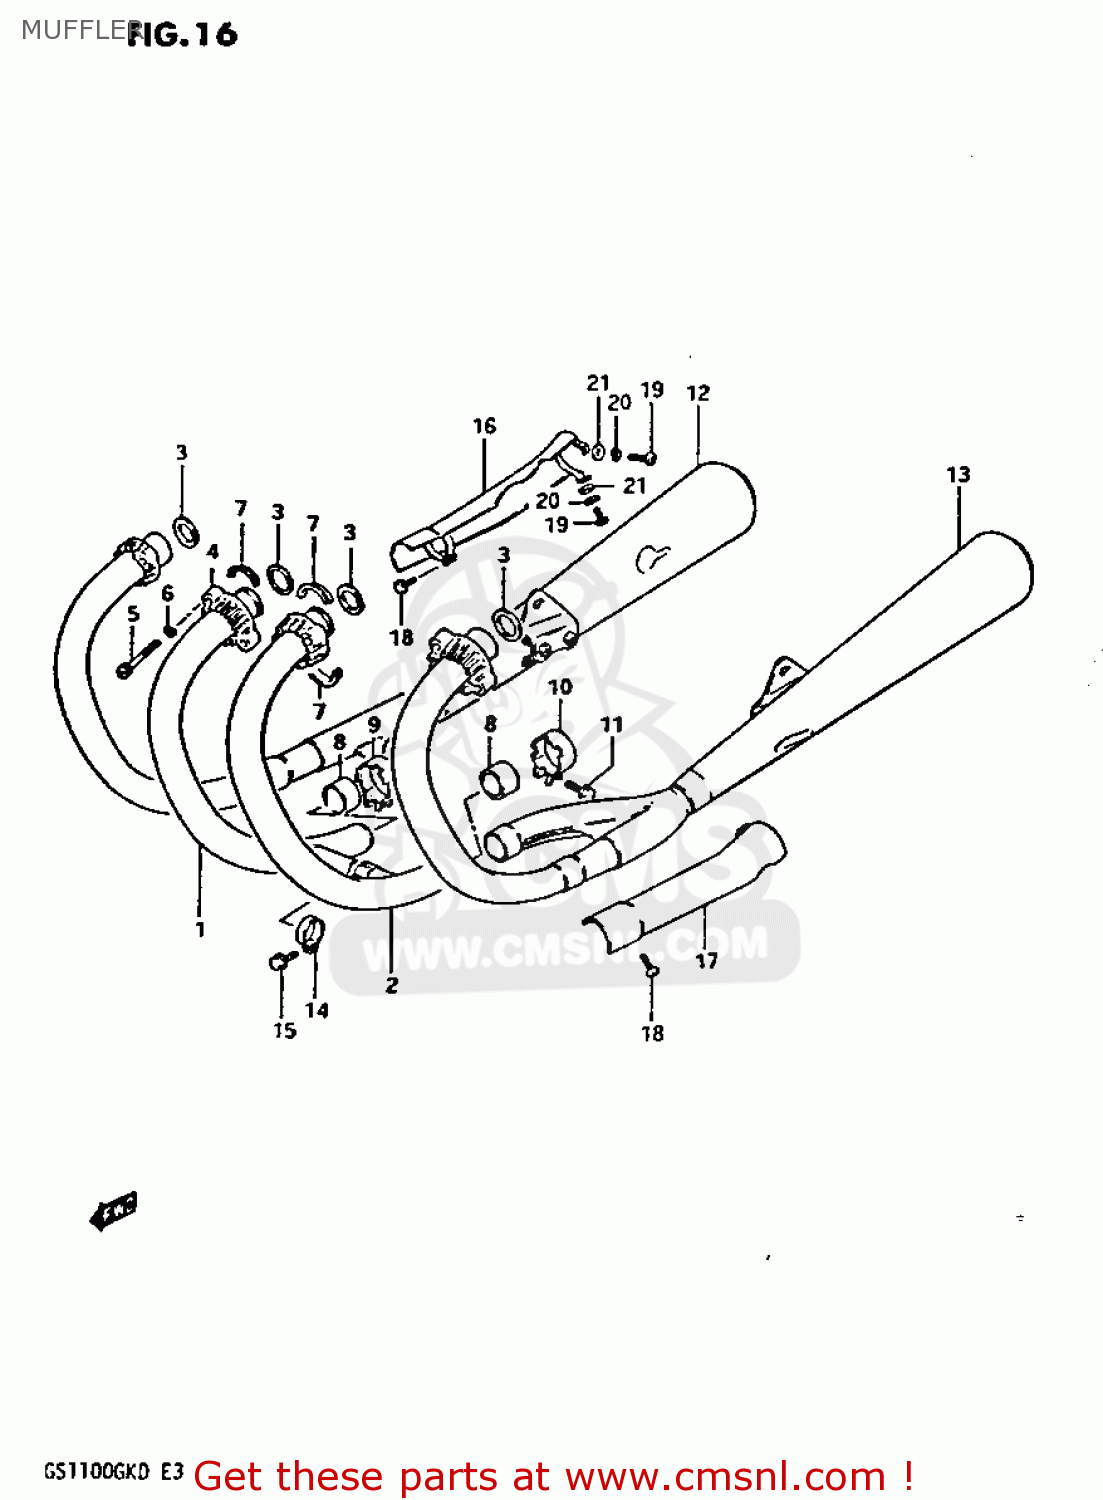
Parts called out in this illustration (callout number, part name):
1	PIPE,EXHAUST,CENTER,RIGHT
2	PIPE,EXHAUST,CENTER,LEFT
3	GASKET,EXHAUST PIPE (NAS)
4	CLAMP(H:21)
5	BOLT
6	LOCK WASHER
7	PLATE,EXHAUST P
8	CONNECTOR,MUFFLER
9	CLAMP,MUFFLER CONNECTOR,R
10	CLAMP,MUFFLER CONNECTOR,L
11	BOLT
12	MUFFLER ASSEMBLY,RIGHT
13	MUFFLER L
14	CLAMP
15	BOLT 6X25
16	COVER,MUFFLER,RIGHT
17	COVER,MUFFLER,LEFT
18	SCREW
19	SCREW
20	WASHER,LOCK
21	WASHER
